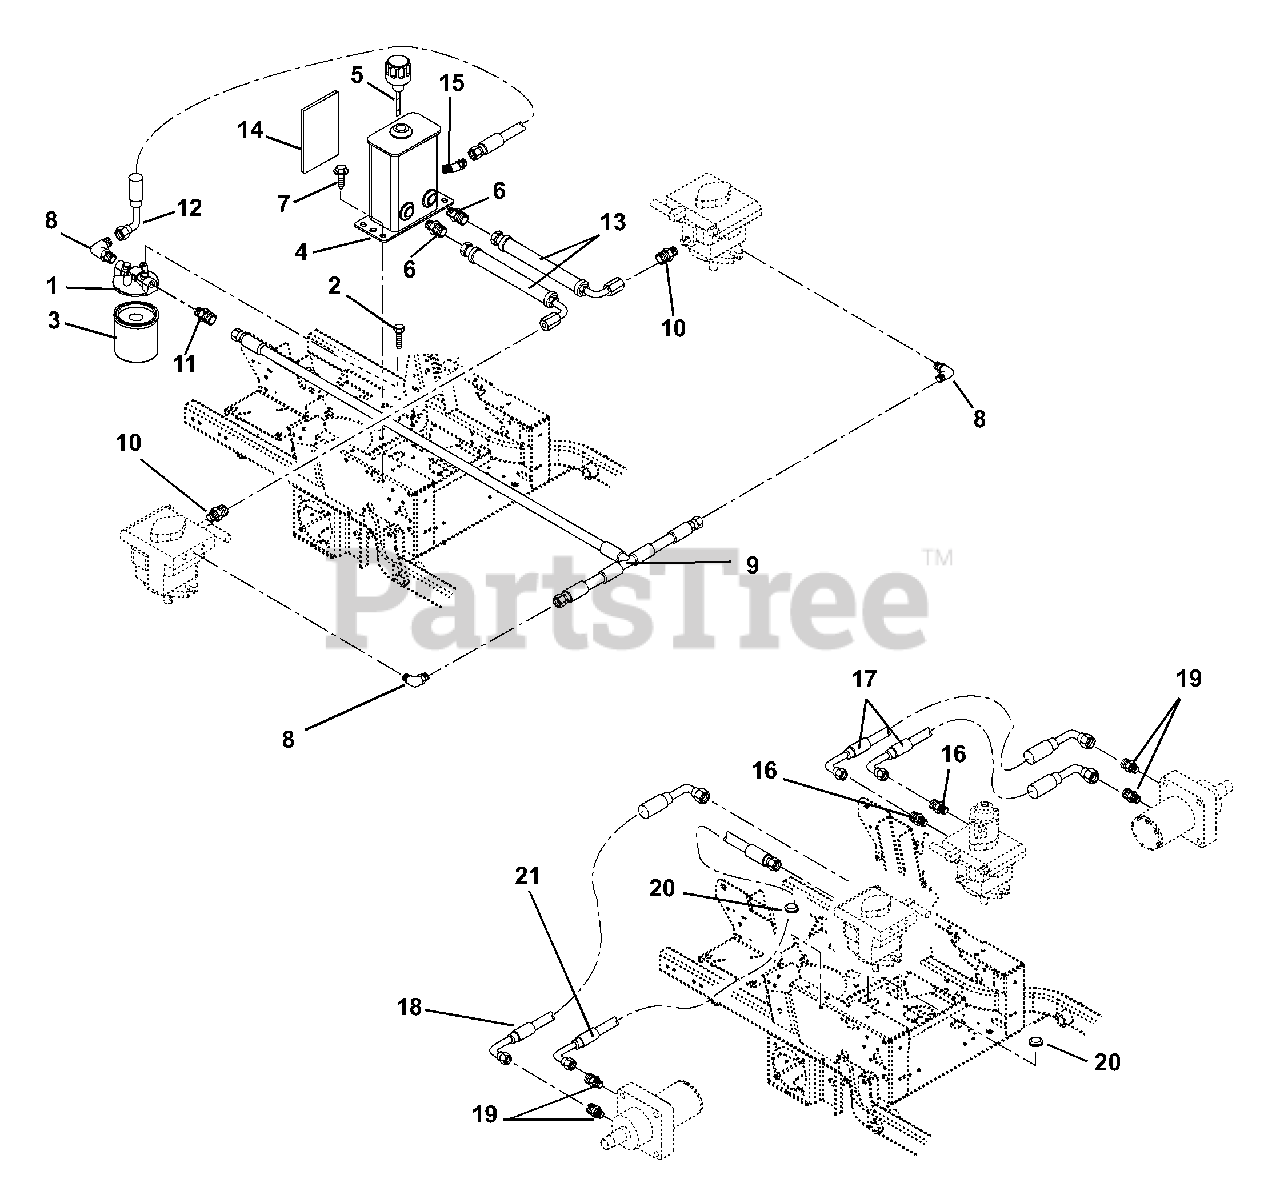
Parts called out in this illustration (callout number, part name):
1	Head, Filter
2	Bolt, Hex .25-20 x .50 Grade 5 Epoxy
3	Oil Filter
4	Tank, Hydraulic
5	Hydraulic Tank Dipstick
6	Fitting, Hydraulic Straight M8O-M4F
7	Screw, Tapping .38-16 x .75 Hex Washer Head
8	Fitting, Hydraulic
9	Hose, Hydraulic
10	Fitting, Hydraulic
11	Fitting, Hydraulic
12	Hose, Hydraulic Valve To Tank
13	Hose, Hydraulic
14	Shield, Heat 5.50 x 4.50
15	Fitting, Hydraulic 45 Degree
16	Adapter, Hydraulic
17	Hose, Hydraulic
18	Hose, Hydraulic
19	Adapter, Hydraulic
20	Grommet, 1.25
21	Hose, Hydraulic
